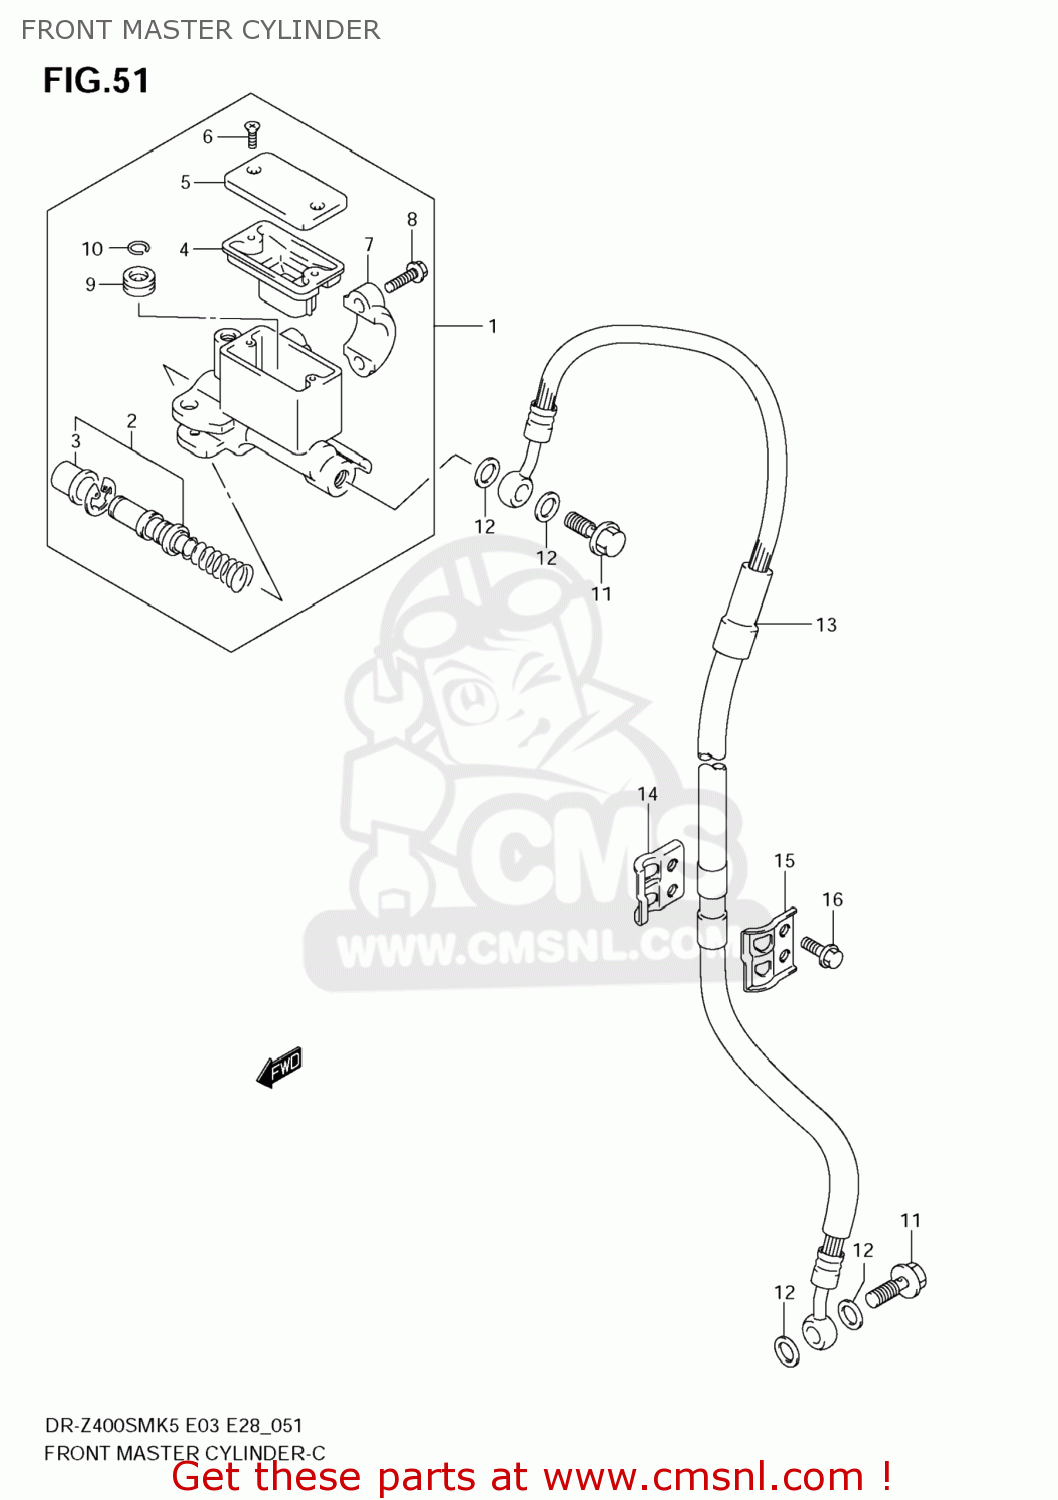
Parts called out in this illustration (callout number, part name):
1	CYLINDER ASSY,FR MASTER
2	PISTON/CUP SET
3	BOOT
4	DIAPHRAGM
5	CAP
6	SCREW
7	HOLDER
8	BOLT
9	SEPARATOR
10	RING
11	BOLT UNION
12	WASHER(10X15X1.5)
13	HOSE,FR BRAKE
14	CLAMP,FR BRAKE HOSE INNER
15	CLAMP,FR BRAKE HOSE OUTER
16	BOLT(6X16)
